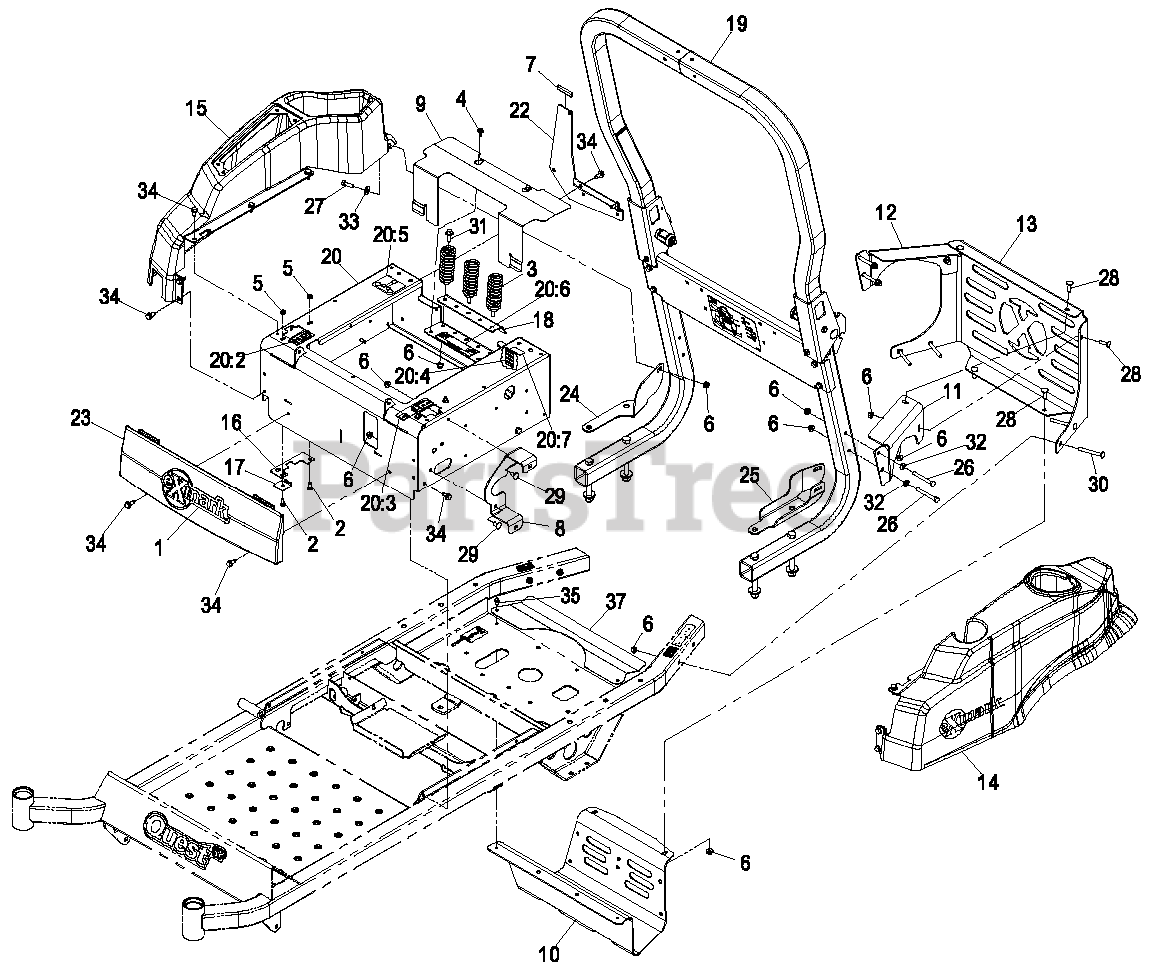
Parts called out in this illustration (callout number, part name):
1	DECAL, EXMARK LOGO
2	BOLT-CARR
3	SPRING-COMPRESSION
4	SCREW-HHF
6	NUT-HF, NI
8	BRACKET-TANK MOUNT
9	COVER-HYDRO FAN
11	PANEL-SIDE STYLING, LH
12	PANEL,SIDE STYLING RH
13	PANEL-STYLING, REAR
14	FENDER,EXMARK LH
15	FENDER,EXMARK RH
16	PLATE,NEUTRAL
17	PLATE,TRACKING
18	CATCH,SEAT LATCH
20	SEAT BOX ASM-W/ DECALS
20:2	DECAL-MOTION CONTROL
20:3	DECAL-CONTROL BRAKE
20:4	DECAL,FUSE BLOCK
20:5	DECAL-ROUTING, BELT
20:6	DECAL,BELT DRIVE
22	BRACKET,FENDER SUPPORT
23	PANEL-FRONT
24	BRACKET,COVER RH
25	BRACKET,COVER LH
26	SCREW-HH
27	SCREW-HH
28	BOLT-CARR
29	SCREW-CARR
30	SCREW-CARR
31	SCREW-HHF
32	WASHER-SPRING
33	WASHER-FLAT
34	Screw-HWH 5/16-18 X 3/4 Tf
35	SCREW-HWH
37	SHIELD-HEAT
